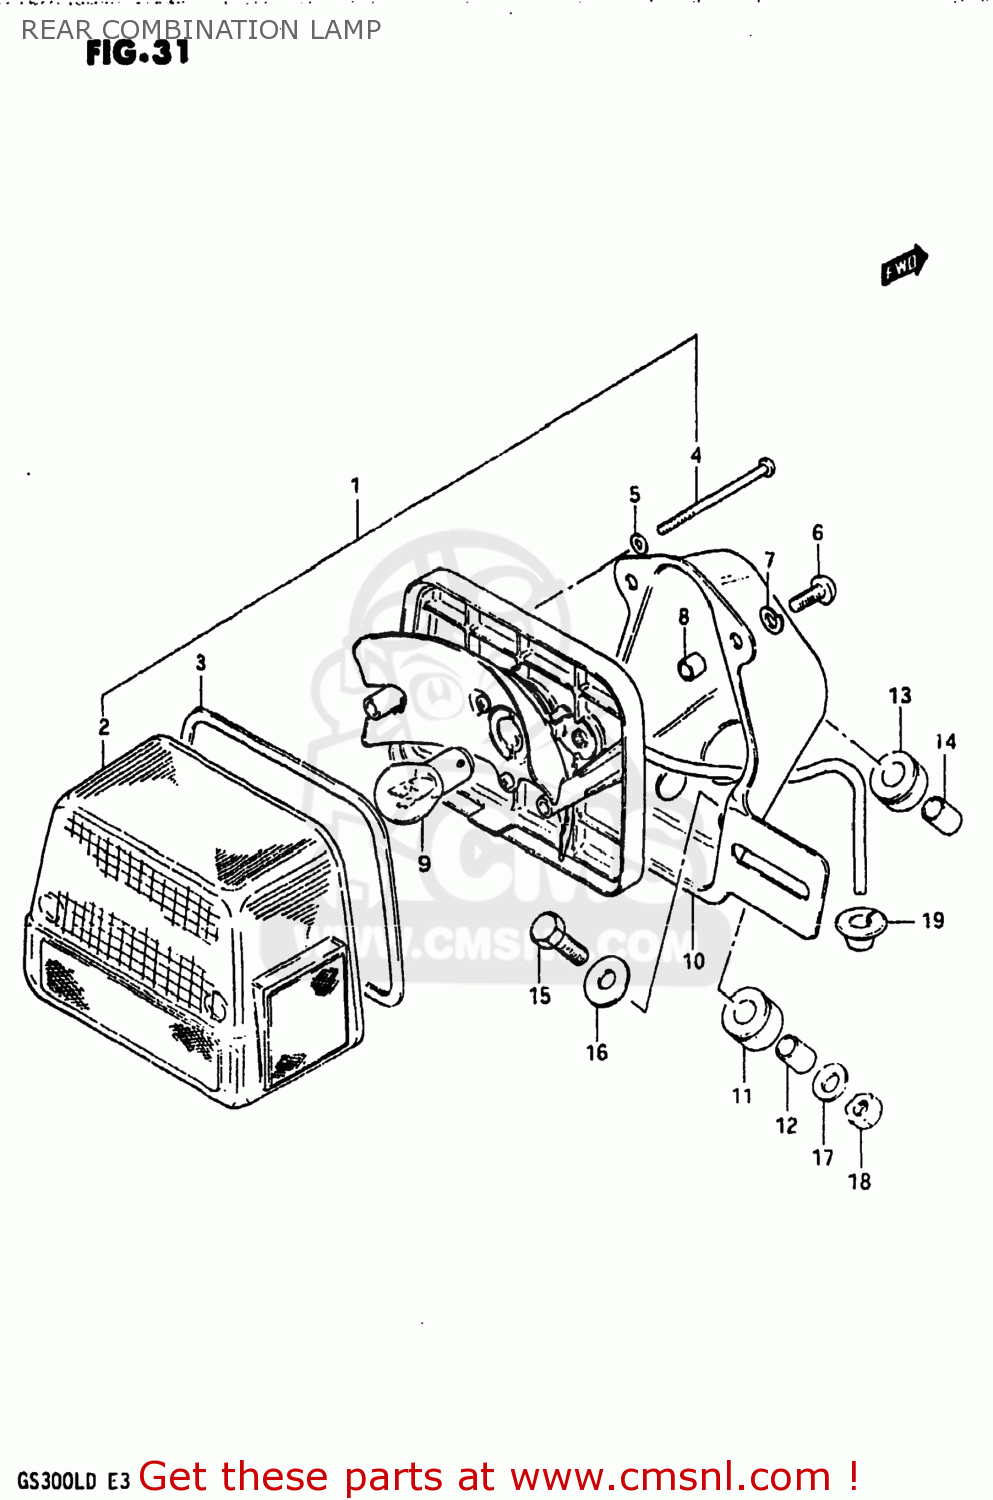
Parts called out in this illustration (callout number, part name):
1	LAMP UNIT,RR COMBNATION
2	LENS
3	GASKET (NAS)
4	SCREW
5	GASKET (NAS)
6	SCREW
7	LOCK WASHER
8	SPACER
9	BULB(12V23W)
10	BRACKET,REAR COMBINATION LAMP
11	CUSHION,REAR COMBINATION LAMP
12	SPACER,REAR COMBINATION LAMP
13	CUSHION
14	SPACER
15	BOLT
16	WASHER (6.5X20X1.2)
17	WASHER
18	NUT
19	GROMMET
